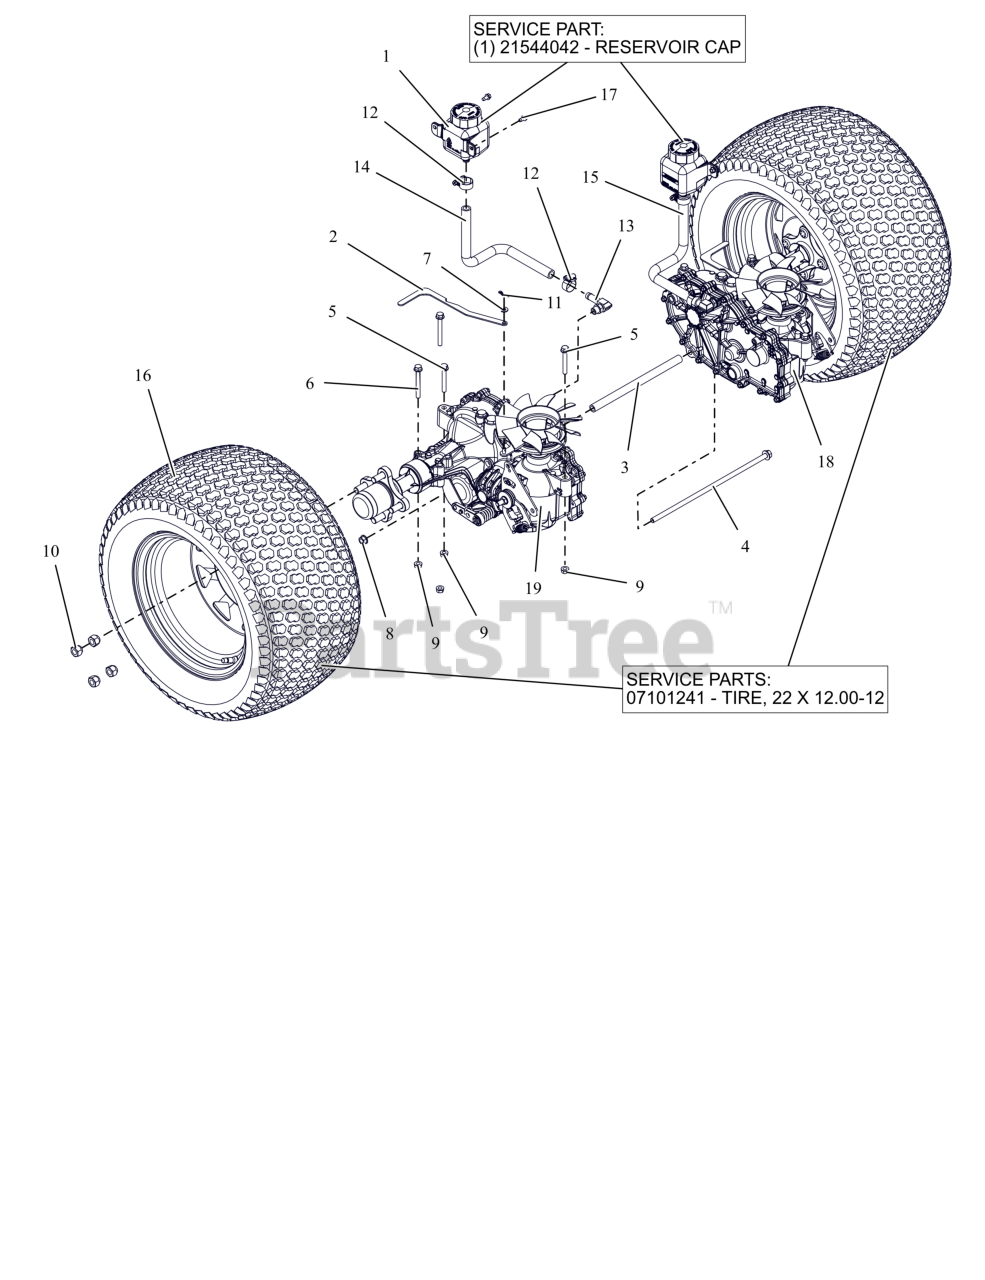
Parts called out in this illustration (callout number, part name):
1	TANK, EXPANSION
1	CAP, HYDRO RESERVOIR REPLAC.
2	BRKT, VALVE DUMP
3	SPCR,TRANS. .406IDX.63ODX9.95L
4	BLT,HEX-FLG .38-16X13 G5 ZCC
5	BLT,HEX-FLG .31-18X2.25 G5 ZCC
6	BLT,HEX-FLG .31-18X2.75 G5 ZCC
7	WSHR,FLT .281X.625X.065 ZCC
8	NUT-LK-TOP-FLG .38-16 ZC120
9	NUT,LK-CTR-FLG .31-18 GF ZCC
10	NUT, WHEEL .50-20 ZCC
11	PIN, HAIR #225 .072X1.09
12	CLAMP,.88 DIA. HOSE
13	FITTING, HYD (90 DEG)
14	HOSE, FORMED EXPANSION -HD RH
15	HOSE, FORMED EXPANSION -HD LH
16	ASM, WHL/TIRE 22X12.00-12 K500
16	TIRE, 22X12.00-12
16	VALVE STEM ASS'Y
16	TIRE TUBE 22,23,24/8.50/9.50/10.00/10.50/12.00-12 4 PLY TR13 STRAIGHT VALVE
17	SCR-TAP .25-20X.50 HWH ZCC
18	TRANSAXLE, ZT3200 - LH
19	TRANSAXLE, ZT3200 - RH
